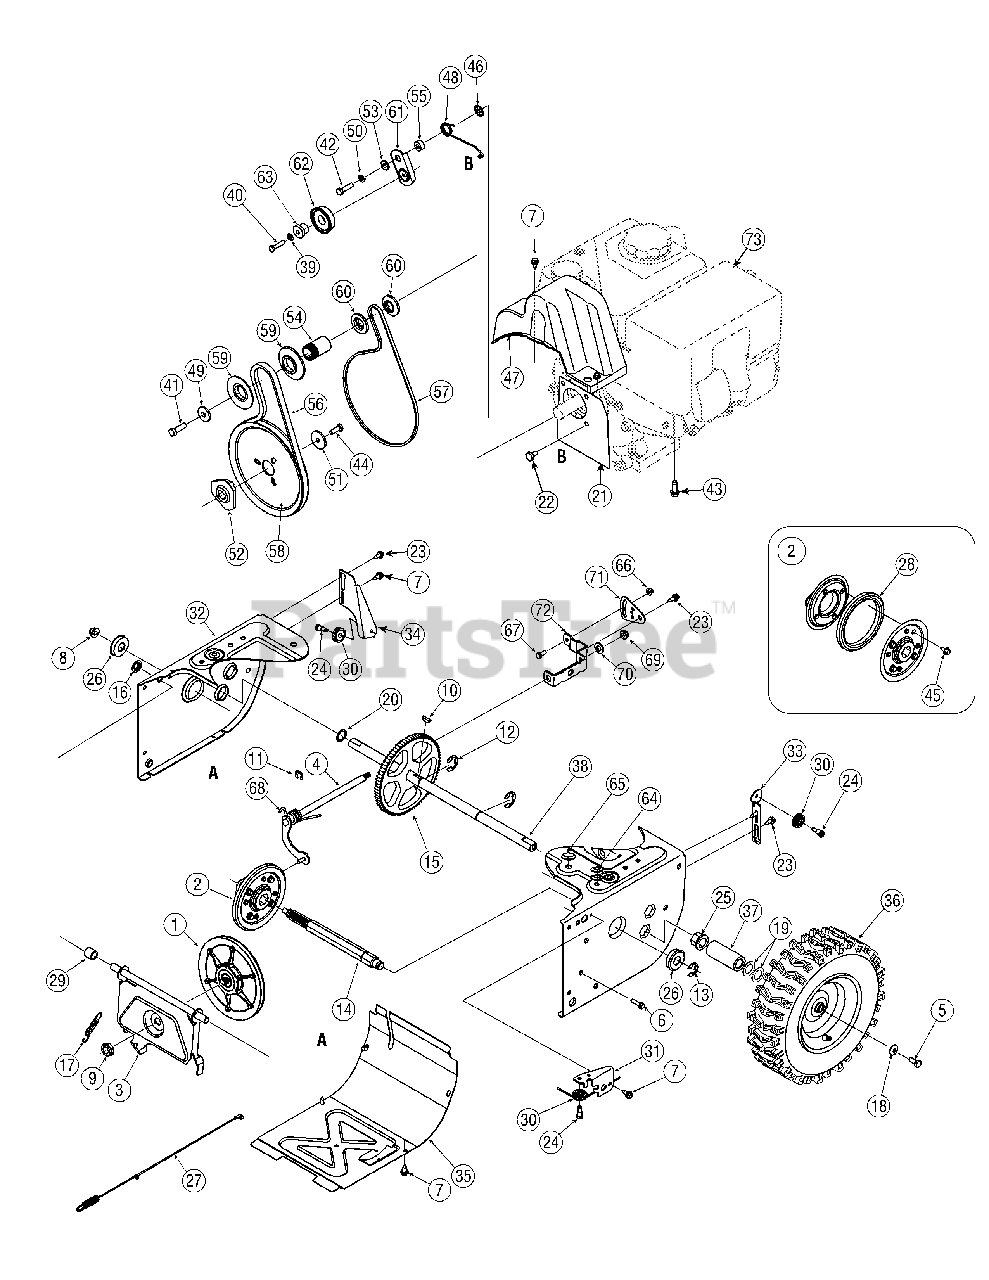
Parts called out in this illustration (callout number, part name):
1	Disc Assembly, Friction Wheel
2	Friction Wheel Assembly, 5.5 OD
3	Support Bracket, Friction Wheel
4	Shift Assembly, Rod
5	Hex Screw, 5/16-24, .750, Gr5
6	Screw, 1/4-20, 1.000
7	Screw, 1/4-20 x .625
8	Nut, Flange Lock, 3/8-16, Nylon
9	Nut, Flange, 5/8-18
10	Key, Hi Pro, 3/16 x 3/4 Dia.
11	E-ring, .500 Dia.
12	E-ring, Retaining, .875 Dia.
13	E-ring, .750 Dia.
14	Hex Shaft, .8125, 7-Tooth
15	Gear, 80-Tooth
16	Speed Nut, .500
17	Extension Spring
18	Washer, Bell, .340 x .872 x .060
19	Washer, Flat, .793 x 1.24 x .060
20	Washer, Flat, .75 x 1.00 x .060
21	Plate, Cover
22	Shoulder Screw
23	Screw, Shoulder, .37 x .105, 1/4-20
24	Screw, 1/4-28, .375
25	Bearing, Hex Flange x .75 ID
26	Bearing, Ball, 17 x 40 x 12
27	Clutch Cable, Wheel, 44.95"
28	Rubber, Friction Wheel, 5.5 OD
29	Spacer, .508 ID x .75 OD x .68
30	Roller, Cable
31	Front Guide Bracket, Auger Cable
32	Frame
33	Guide Bracket, Auger Cable
34	Guide Bracket, Drive Cable
35	Cover, Frame
36	LH Wheel Assembly
36	RH Wheel Assembly
37	Spacer, 1.25 x .75 x 3.0
38	Axle, .75 x 22"
39	Washer, Lock, 1/4
40	Hex Screw, 1/4-20, 1.25, Gr5
41	Hex Screw, 3/8-24, 1.25, Gr8
42	Hex Screw, 5/16-24, 1.25, Gr5
43	Screw, Sems, 3/8-16, 1.00
44	Hex Screw, 5/16-24, .875, Gr8
45	Screw, 1/4-20 x .625
46	Nut, Push-on, .25 Dia.
47	Cover, Belt
48	Spring, Torsion, .850 ID x .354
49	Washer, Flat, .406 x 1.25 x .157
50	Washer, Lock .3125
51	Washer, Flat, .34 x 1.50 x .150
52	Pulley, Adapter, .75 Dia.
53	Spacer, Shoulder, .317 x .50 x .102
54	Spacer, .875 ID x 1.185 OD
55	Spacer, .340 x .750 x .360
56	Belt, Auger Drive
57	Belt, Wheel Drive
58	Pulley, Auger Drive, 8.1 x .5
59	Pulley, Half, V x 2.600 OD
60	Pulley, Half, 3/8-V x 1.7160 OD
61	Idler Bracket, Wheel Drive
62	Idler Pulley Assembly
63	Spacer, Shoulder, .26 x .79 x .538
64	Plug, 3/8 ID
65	Plug, 1/2 ID
66	Nut, Flange Lock, 1/4-20, Nylon
67	Hex Screw, 1/4-20, .620, Gr5
68	Spring, Torsion, .750 ID x .968
69	Nut, Flange Lock, 5/16-18, Nylon
70	Wash., Flat, .469 x .875 x .105
71	Pivot Bracket, Speed Selector
72	Shift Bracket, Speed Selector
73	Replacement Engine
